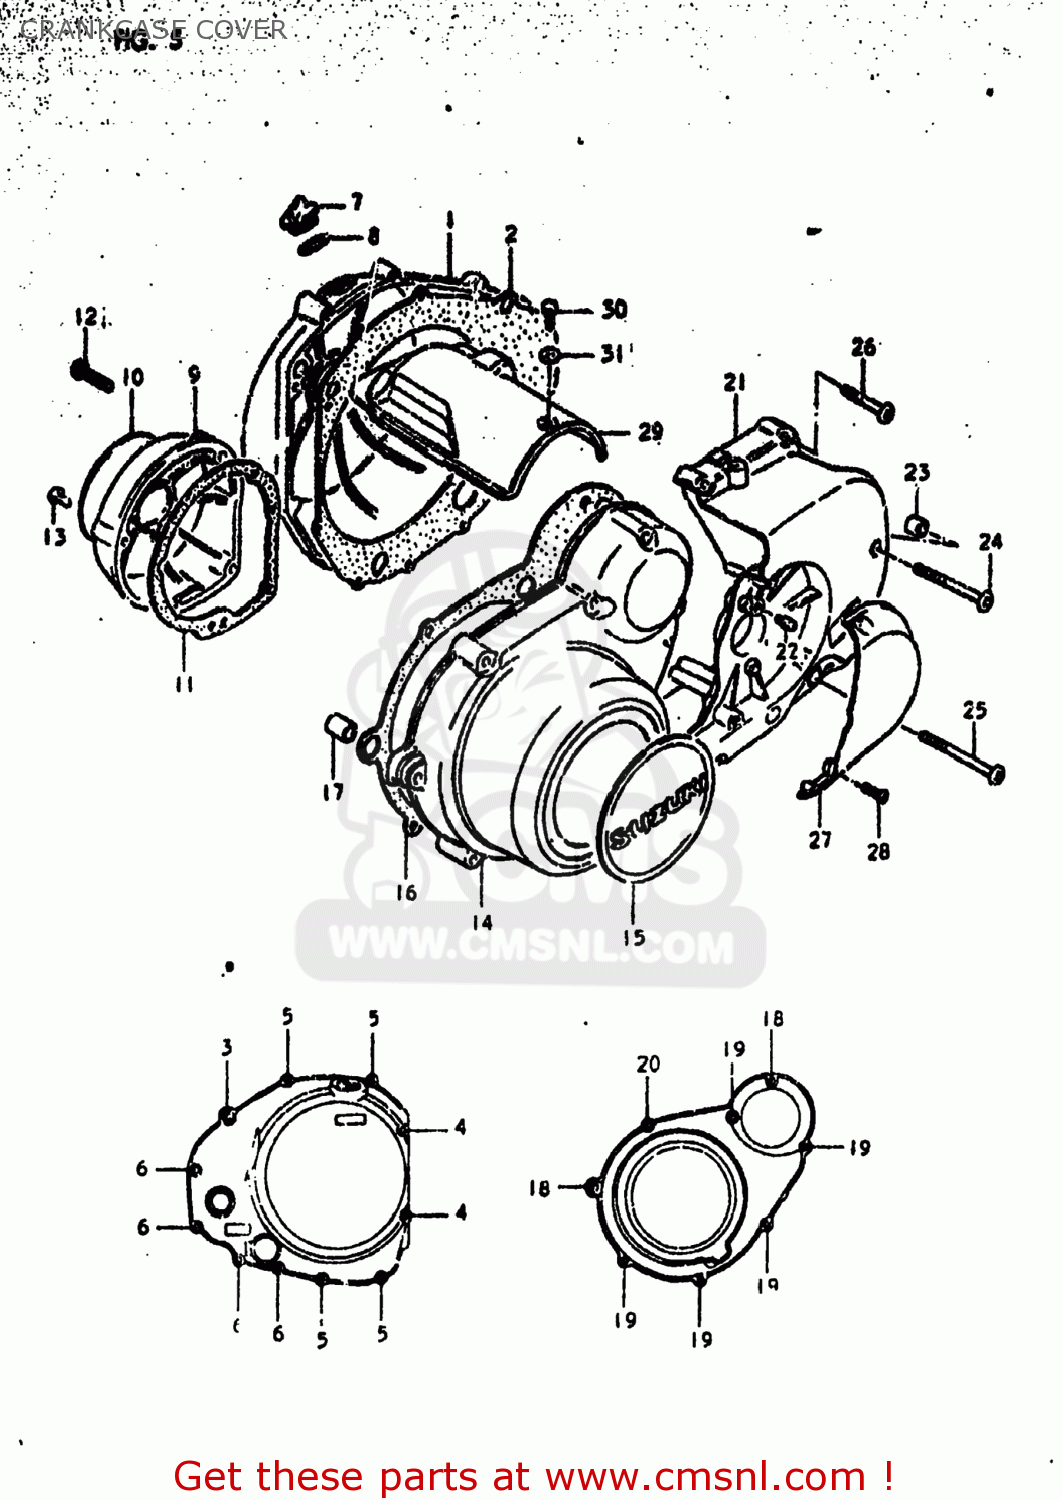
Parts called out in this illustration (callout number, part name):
1	COVER,CLUTCH
2	GASKET,CLUTCH COVER (MCA)
3	SCREW
4	SCREW
5	SCREW
6	SCREW
7	CAP
8	O RING(D:2.2,ID:32)
9	COVER,CONTACT BREAKER
10	EMBLEM
11	GASKET,CONTACT BREAKER COVER (NAS)
12	SCREW
13	SCREW
14	COVER
15	EMBLEM
16	GASKET,MAGNETO COVER (MCA)
17	PIN
18	SCREW (6X45)
19	SCREW
20	SCREW (6X35)
21	CRANKCASE SET
22	NIPPLE
23	PIN
24	SCREW
25	SCREW 6X80
26	SCREW 6X30
27	CAP,CLUTCH RELEASE ADJUST
28	SCREW
29	COVER,STARTER MOTOR
30	BOLT
31	WASHER
